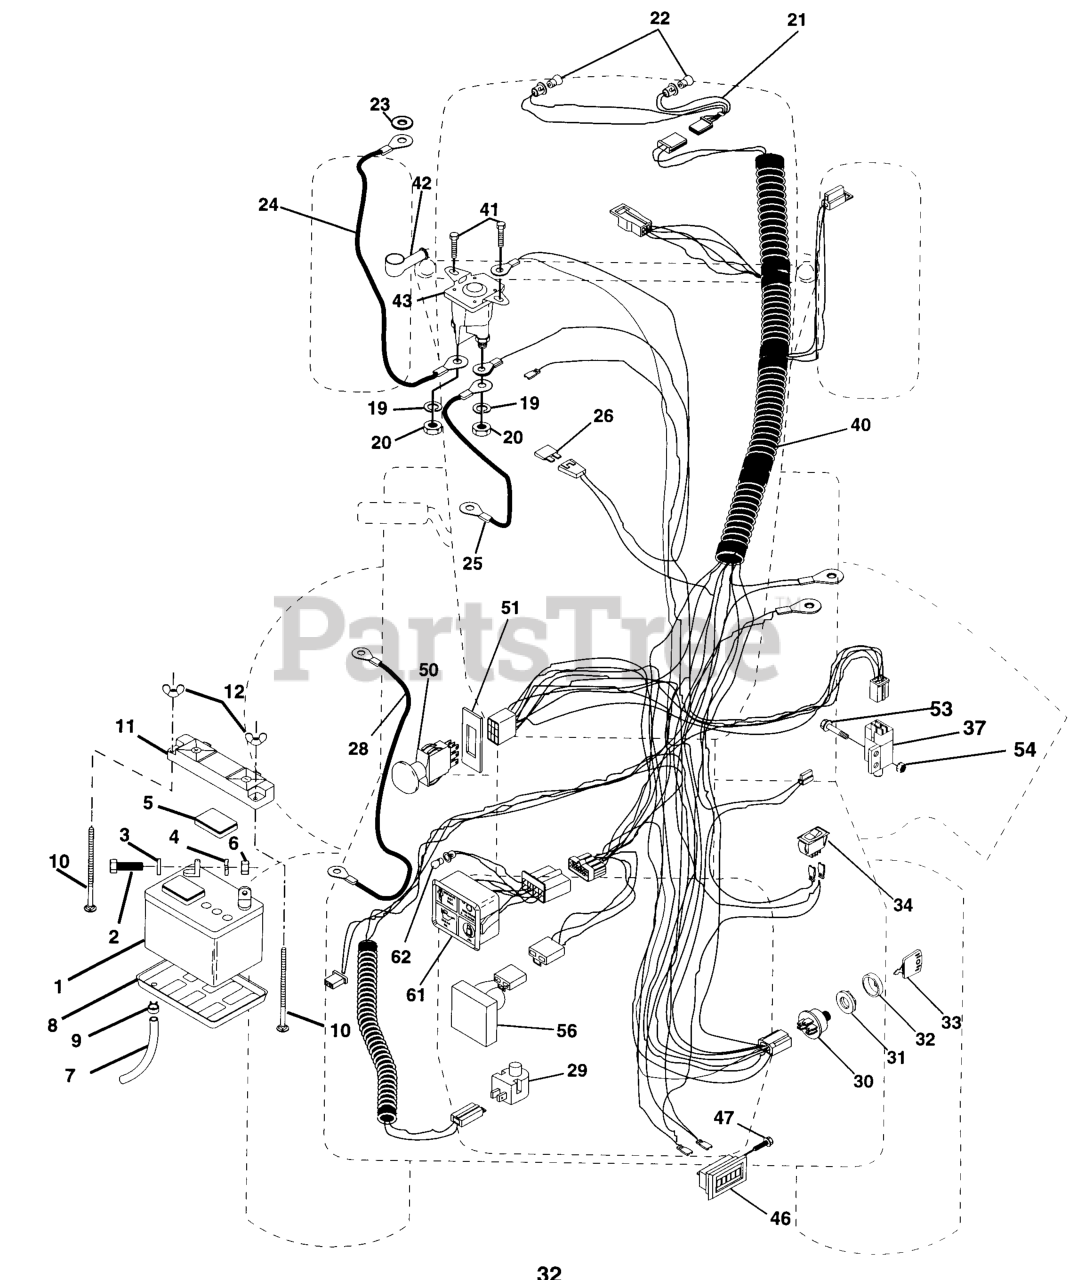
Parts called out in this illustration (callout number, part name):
1	BATTERY
2	BOLT.HEX.1/4.X.3/4.DICHROMATE
3	LOCKWASHER
4	WASHER
5	CAP BATTERY NLA
6	NUT
7	PLASTIC TUBE
8	BATTERY TRAY T
9	HOSE CLAMP T
11	TERMINAL GRD YTV
12	WING NUT
19	LOCKWASHER
20	NUT
21	HARNESS LIGHT SOC
23	Washer, Lock Int. Tooth 1/4
24	BATTERY CABLE GT
25	CABLE-BATTERY YTV
28	CABLE T
29	RP.SWITCH.PLUNGER.NC.GRAY
30	IGNITION SWITCH
31	NUT, IGNITION
32	COVER SWITCH KEY
33	KEY MLD GEN DELTA
37	SWITCH INTERLOCKT
40	IGNITION HARNESS
41	SCREW
42	TERMINAL COVER
43	SOLENOID
46	HOUR METER T
47	Screw #10-24 x 1/2
50	SWITCH-PTO
51	FRAME RETAINING RING
53	SCREW **
54	Nut, Keps #10-32
56	SENSOR LOW VOLTAGE
61	LIGHT PACKAGE
62	BULB LIGHT T
